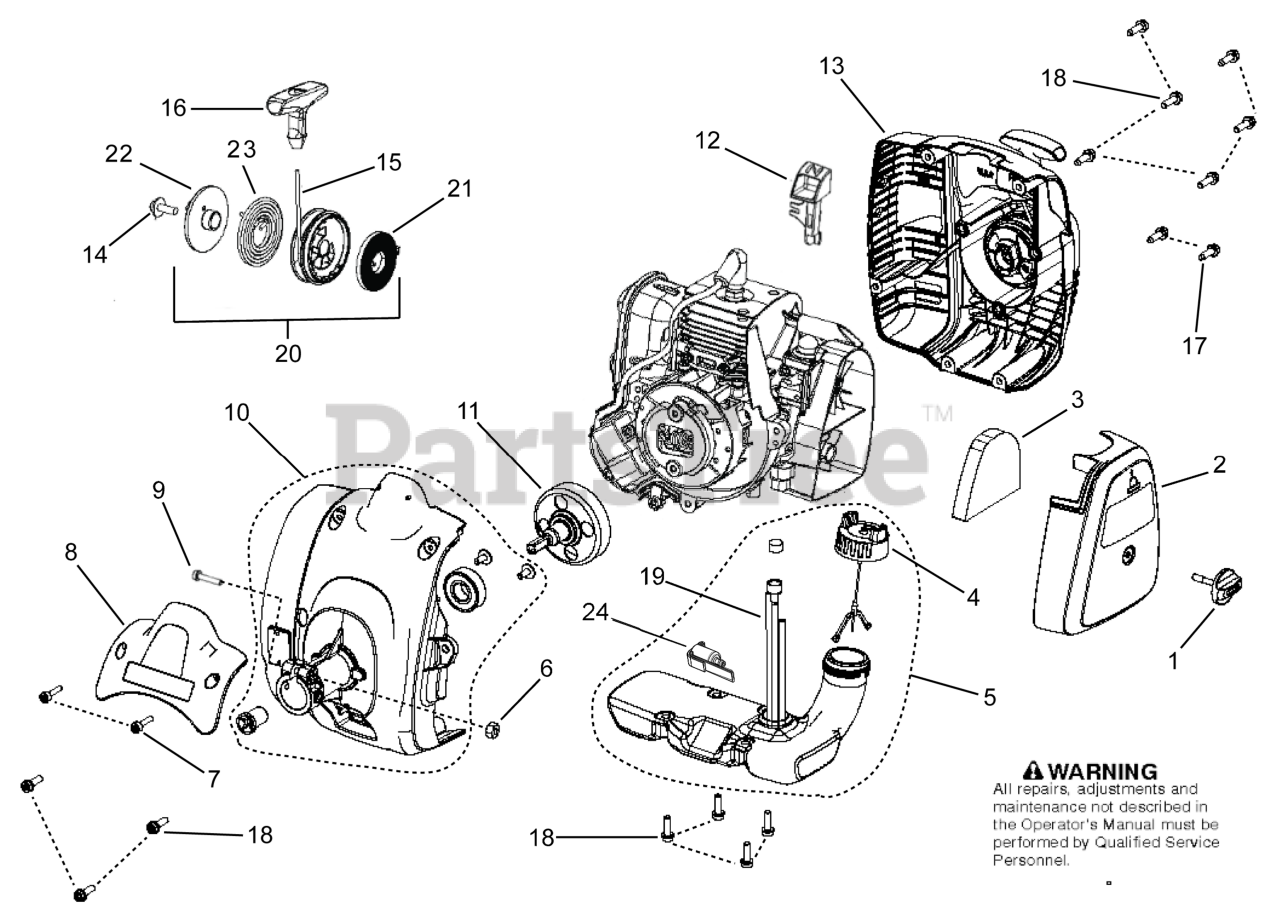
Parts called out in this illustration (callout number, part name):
1	KNOB
2	FILTER COVER
3	FILTER
4	ASSY FUEL CAP
5	KIT FUEL TANK
6	NUT
8	GUARD CLUTCH COVER
10	CLUTCH COVER ASSY
11	Clutch Drums
12	CHOKE BUTTON
13	ASSY STARTER COVER
15	KIT ROPE
16	STARTER HANDLE
19	KIT FUEL LINE
20	KIT PULLEY/SPRING
21	KIT STARTER SPRING
22	PULLEY STARTER DRIVE
23	DRIVER SPRING
24	FUEL FILTER
